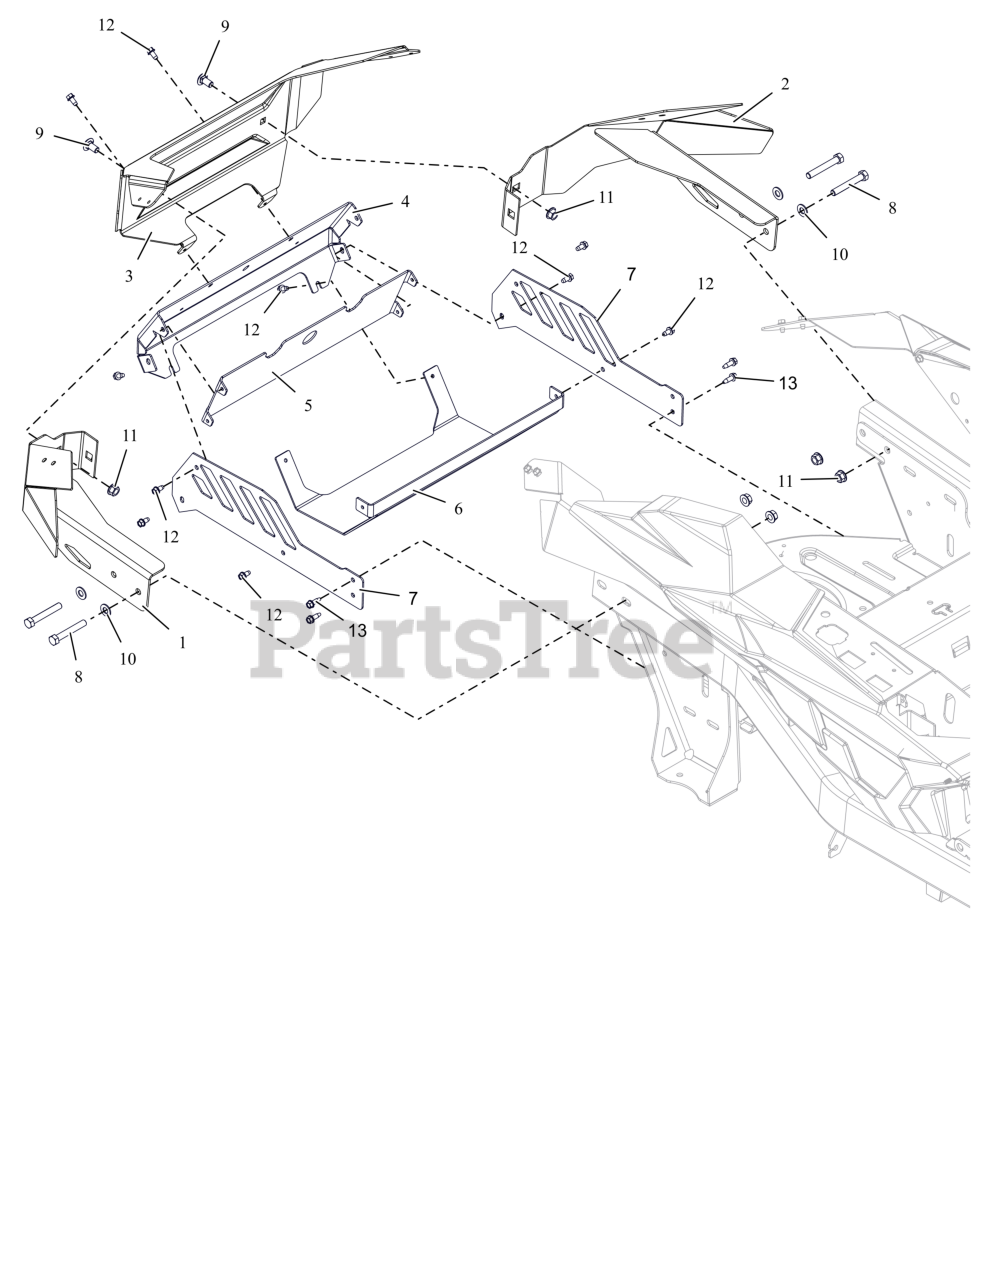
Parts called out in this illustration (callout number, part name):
1	WLDMT, BUMPER - RH (BLACK)
2	WLDMT, BUMPER -LH (BLACK)
3	PLATE- GRAVELY BACK WRAP
4	SHIELD- MUFFLER
5	SHIELD, HEAT (BLACK)
6	MUFFLER- SHEILD- GRASS BROWN
7	KIT, MUFFLER SHIELD W/DECALS
8	BLT, HEX .38-16X2.50 G5 ZCC
9	BTL,RHSSN .375-16 X 0.75 G5 FPB
10	WSHR,FLT .406X.812X.065 ZCC
11	NUT-LK-CTR-FLG .375-16 GF ZCC
12	SCR-TAP .25X.50 HWH ZB500
13	SCR, TAP .25-20.X.75 TT2000 ZB500
